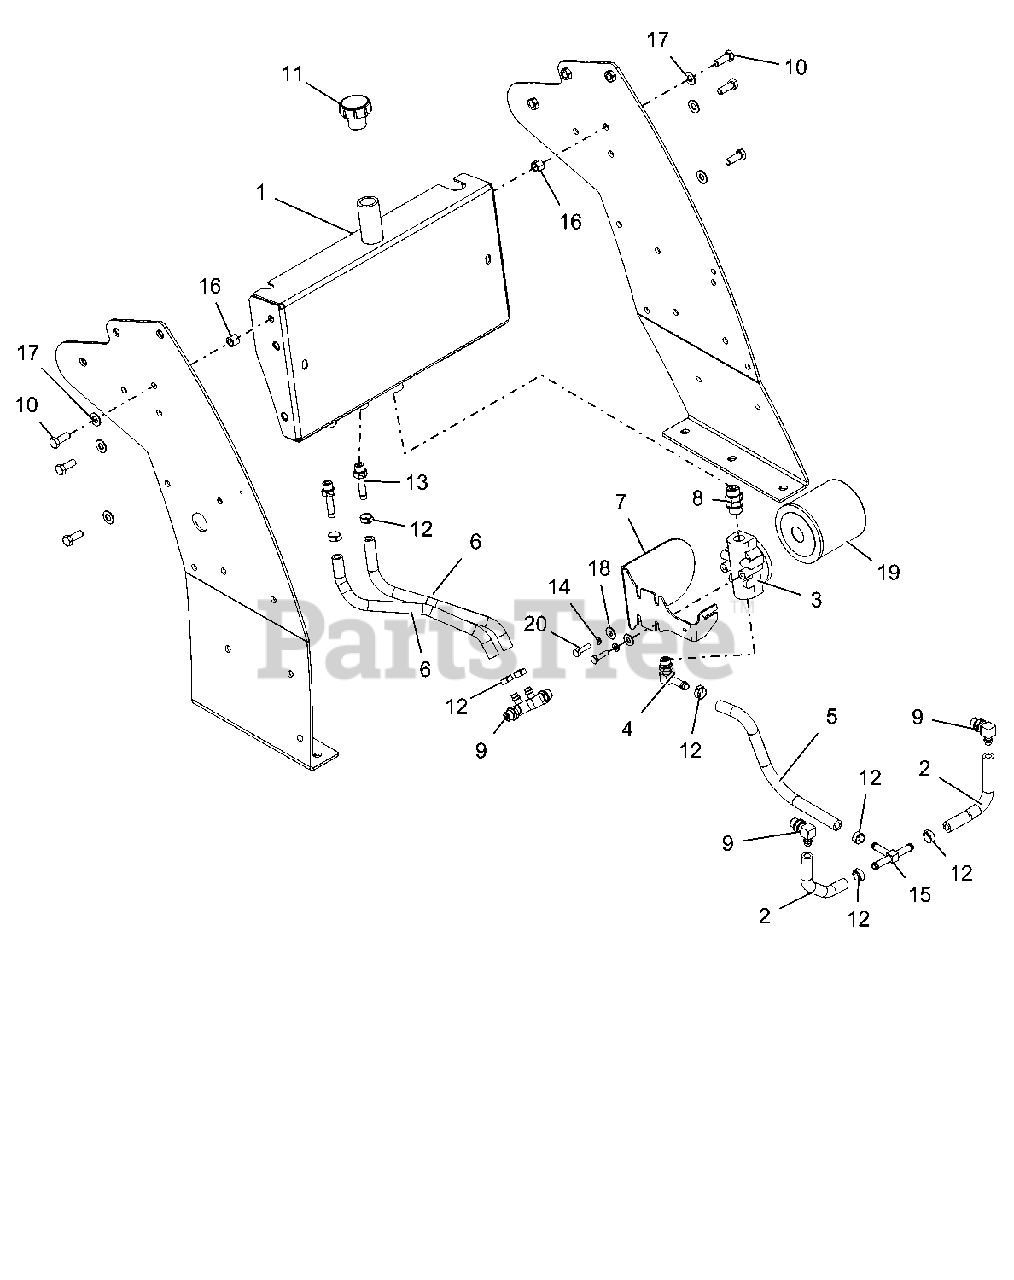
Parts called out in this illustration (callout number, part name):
1	WLDMT, TANK HYDRO STR PORT-RED
2	HOSE, HYD 3/8 X 6.00
3	HEAD, OIL FILTER
4	FTG, 90 BRB-OR 4601-06-08
5	HOSE, HYD .375X10.5
6	HOSE, HYD .375X14.00
7	GUARD, HYDRO FILTER
8	FTG, STR UNION M80-M80
9	FTG, 90 9/16MOR X 3/8HOSE SHRT
10	BLT-HEX .38-16X1.00 GR5 YWZC
11	CAP, OIL FILL BREATHER
12	CLAMP, HOSE - 1/2" PINCH
13	ADAPTER, STRAIGHT FITTING
14	WSHR-LK .25X.062 REG YWZC
15	FTG, TUN 3/8 HOSE
16	NUT-LK-NYL .38-16 YWZC
17	WSHR-FL-STL.406X.812X.065 YWZ
18	WSHR-FL-STL.312X.734X.065 YWZ
19	FILTER, OIL
20	BLT-HEX .25-20X1.00 GR5 YWZC
